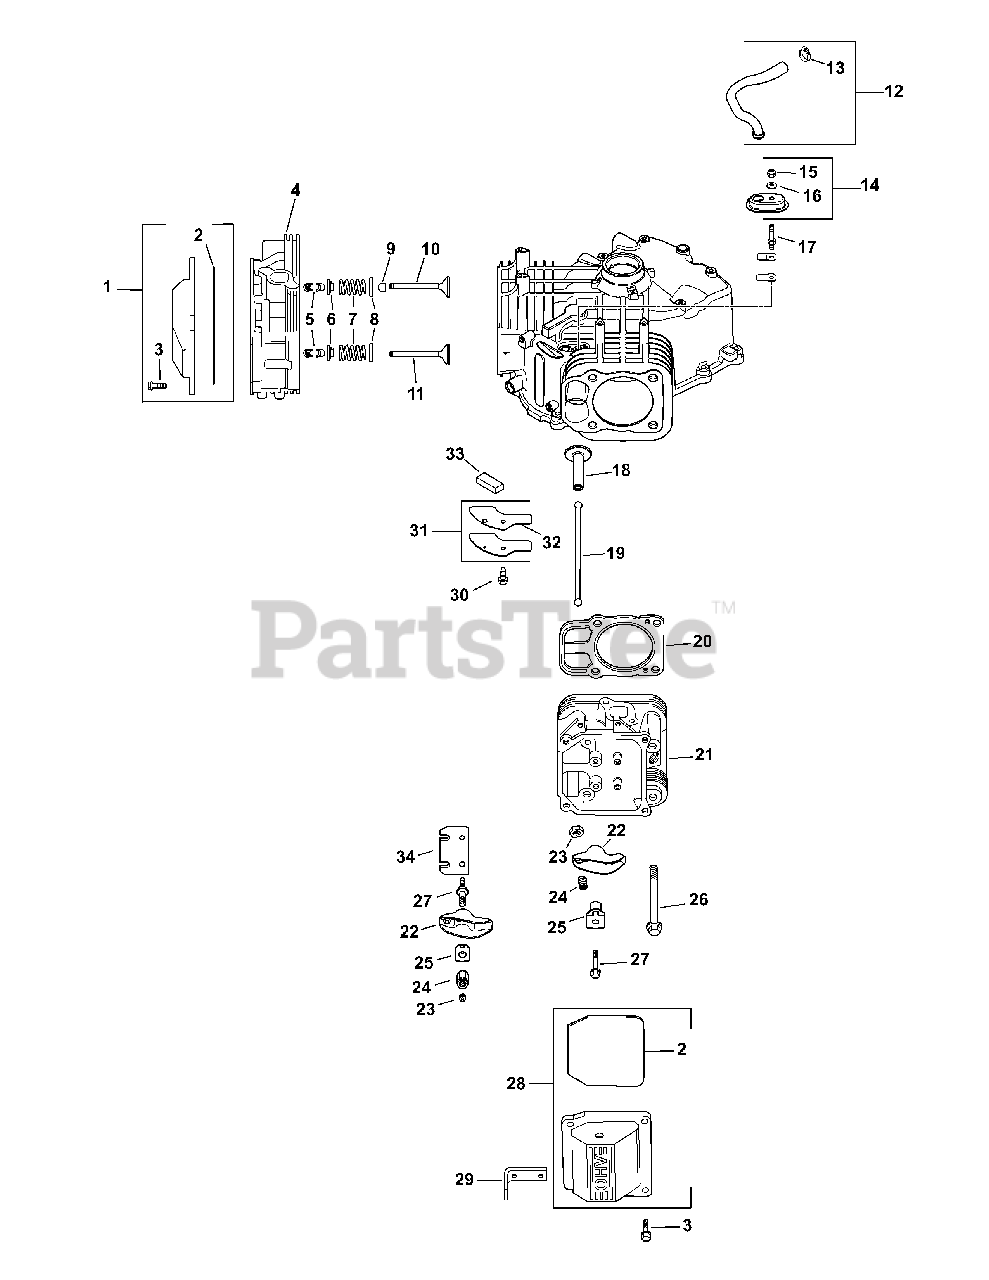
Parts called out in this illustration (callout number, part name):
1	KIT, PLAIN ROCKER COVER
2	O-RING, VALVE COVER
3	SCREW, FLG M6X1.0X30
4	KIT, #1 CYLINDER HEAD ASSY
5	KIT, RETAINER
6	CAP, VALVE SPRING
7	SPRING, VALVE
8	RETAINER, SPRING
9	SEAL, VALVE STEM
10	VALVE, INTAKE (STD)
11	VALVE, EXHAUST (STD)
12	KIT, BREATHER HOSE
13	CLAMP, HOSE
14	KIT, BREATHER HOUSING
15	NUT, LOCK M5X0.8
16	WASHER, SEALING
17	STUD, BREATHER COVER
18	KIT,TAPPET
20	KIT, CYLINDER HEAD GASKET
21	KIT, #2 CYLINDER HEAD ASSY
23	NUT, M10X0.75
24	SCREW, SET
25	PIVOT, ROCKER ARM
26	SCREW, FLG M10X1.5X90
28	KIT, BREATHER VALVE COVER
29	STRAP, LIFTING
30	SCREW, FLG THD FRM M6X1.0X16
31	KIT, BREATHER COVER
32	GASKET, BREATHER COVER
33	FILTER, BREATHER
34	PLATE, GUIDE
